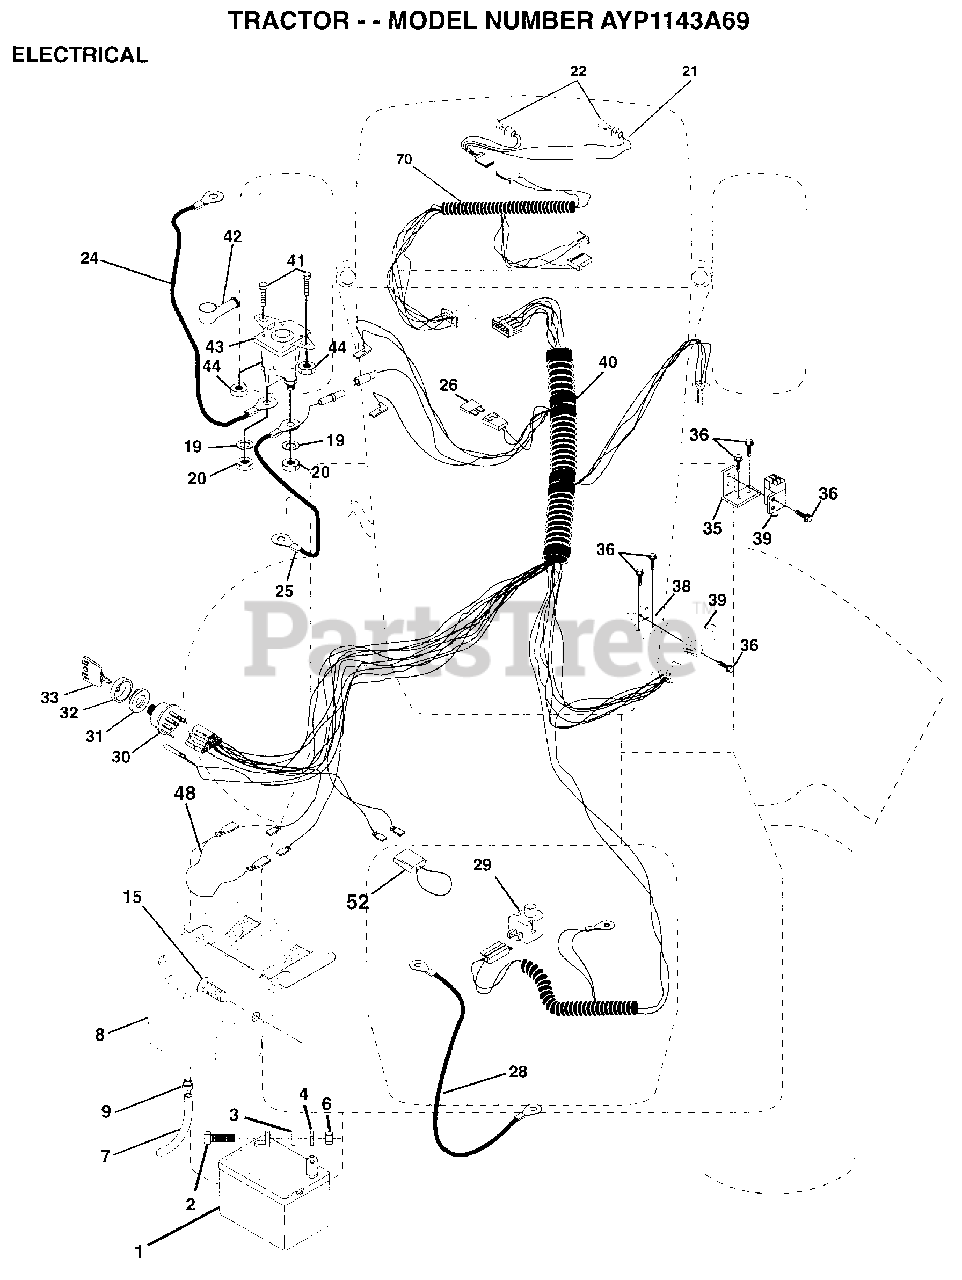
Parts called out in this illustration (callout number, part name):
2	BOLT LT
3	WASHER
4	LOCKWASHER
7	TUBE T
9	HOSE CLAMP T
15	FASTNER.SNAP-IN
20	NUT
21	"HARNESS,LIGHT SOC"
22	HEADLAMP BULB
24	"CABLE T, BATTERY"
25	CABLE.BTRY.6GA.RD
26	FUSE HYT
28	CABLE T
29	SWITCH SEAT
30	SWITCH IGN 4POS
31	NUT IGNITION
32	COVER KEY SWITCH
33	KEY
35	BRACKET LT
36	SCREW
38	BRACKET SWITCH IN
39	SWITCH INTERLOCKT
40	HARNESS.IGNITION
41	BOLT HXHD FIN
44	NUT
48	ADAPTER AMMETER
52	PROTECTION LOOP
70	HARNESS ENGINE
